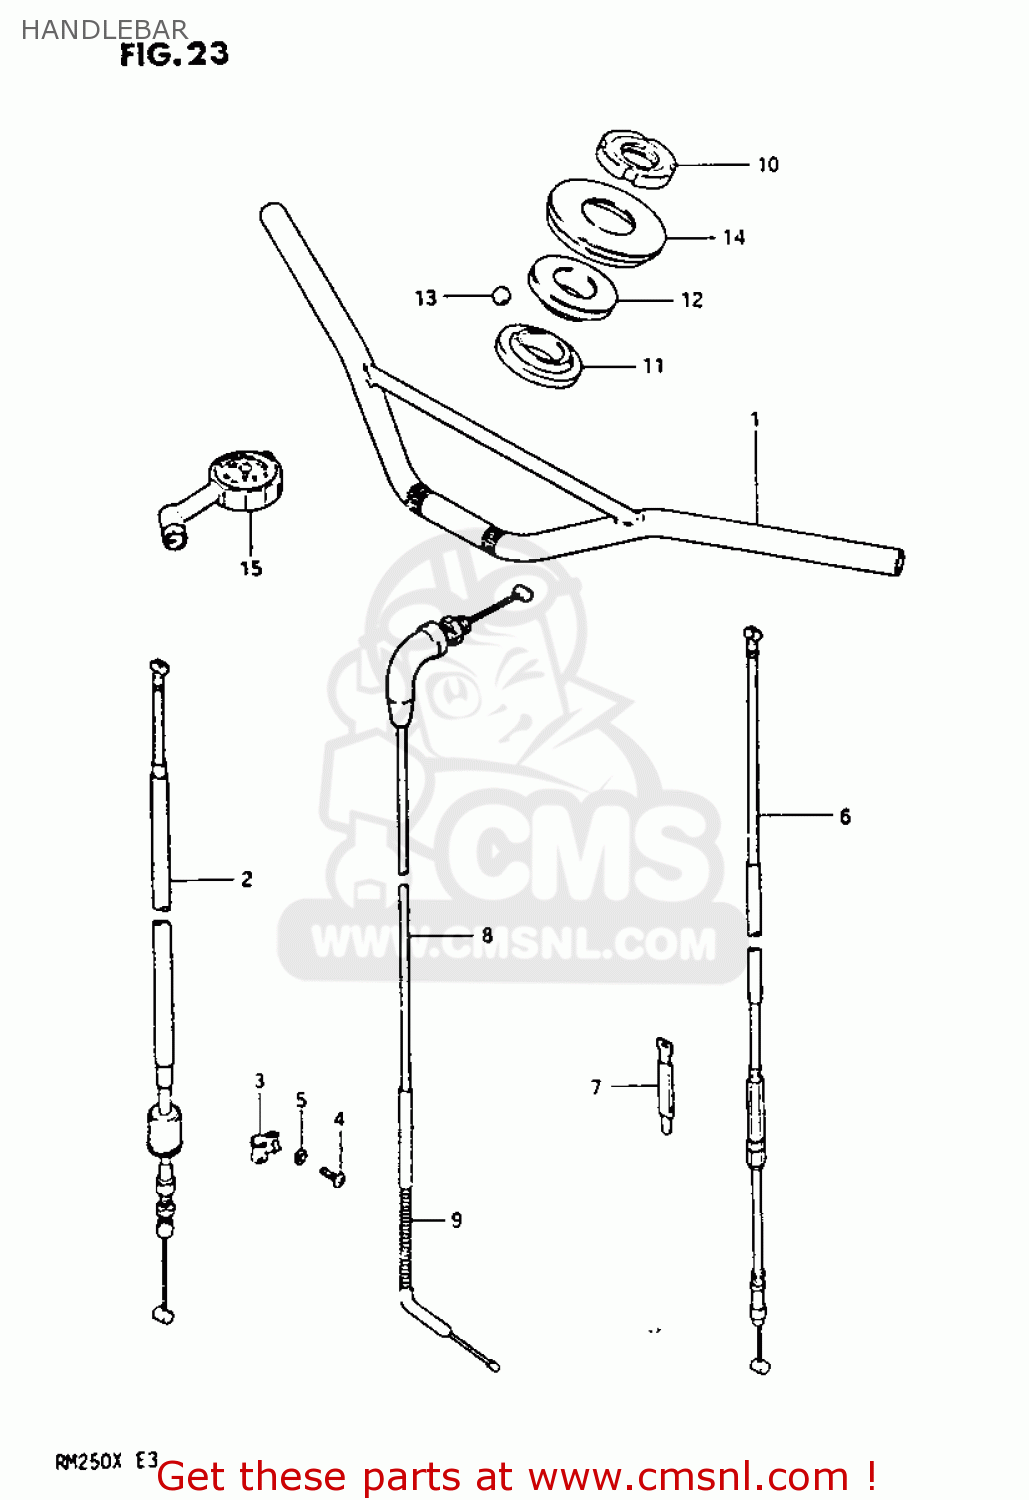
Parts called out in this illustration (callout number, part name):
1	HANDLEBAR
2	CABLE ASSY,FR BRAKE
3	GUIDE,CABLE
4	SCREW
5	WASHER,LOCK
6	CABLE ASSEMBLY,CLUTCH
7	CLAMP
8	CABLE ASSEMBLY,THROTTLE
9	PROTECTOR,CABLE
10	NUT,STEERING STEM
11	RACE,STEERING INNER (SUJ)
12	RACE,STEERING,OUTER,UPPER
13	BALL
14	SEAL,STEERING UPR DUST
15	GAUGE ASSY,AIR PRESSURE
